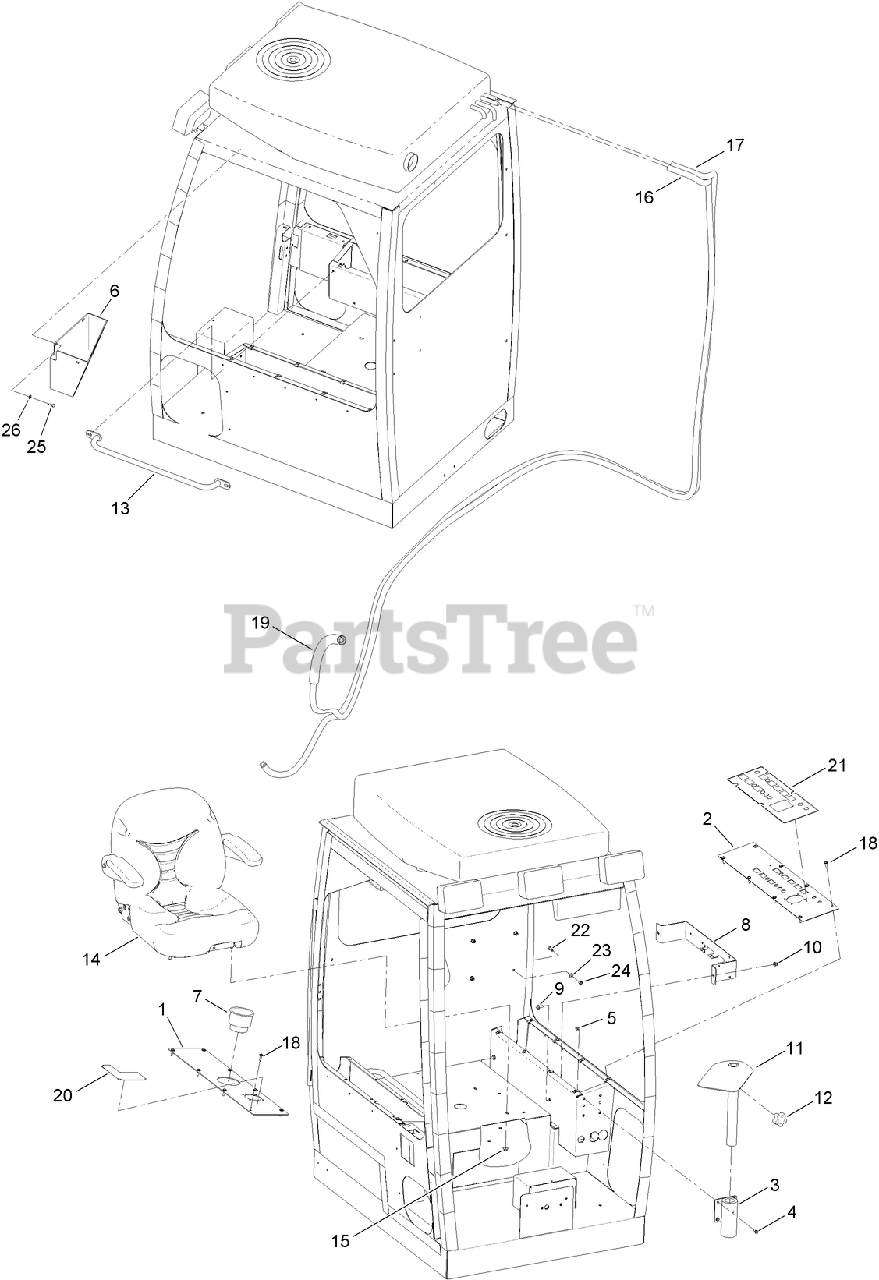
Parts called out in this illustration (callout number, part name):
1	PLATE-CONSOLE, RH
2	PLATE-CONSOLE, LH
3	MOUNT-DISPLAY
4	SCREW-HHF
5	NUT-FLANGE, NI
6	HOUSING-DISPLAY
7	CUP-HOLDER
8	PLATE-MOUNTING, ELECTRICAL
9	SCREW-HHF
10	NUT-LOCK, HHF
11	MOUNT-LOCATOR
12	KNOB-ADJUSTMENT
13	HANDLE-CAB
14	OPERATOR SEAT ASM (STATIC)
15	NUT-HF, NI
16	HOSE-HEATER
17	HOSE-HEATER
18	SCREW-PPH
19	SLEEVE-THERMAL
20	DECAL-JOYSTICK, RIGHT
21	DECAL-JOYSTICK, LEFT
22	SCREW-HH
23	WASHER-PLAIN
24	NUT-LOCK, NI
25	SCREW-HH
26	WASHER-FLAT
